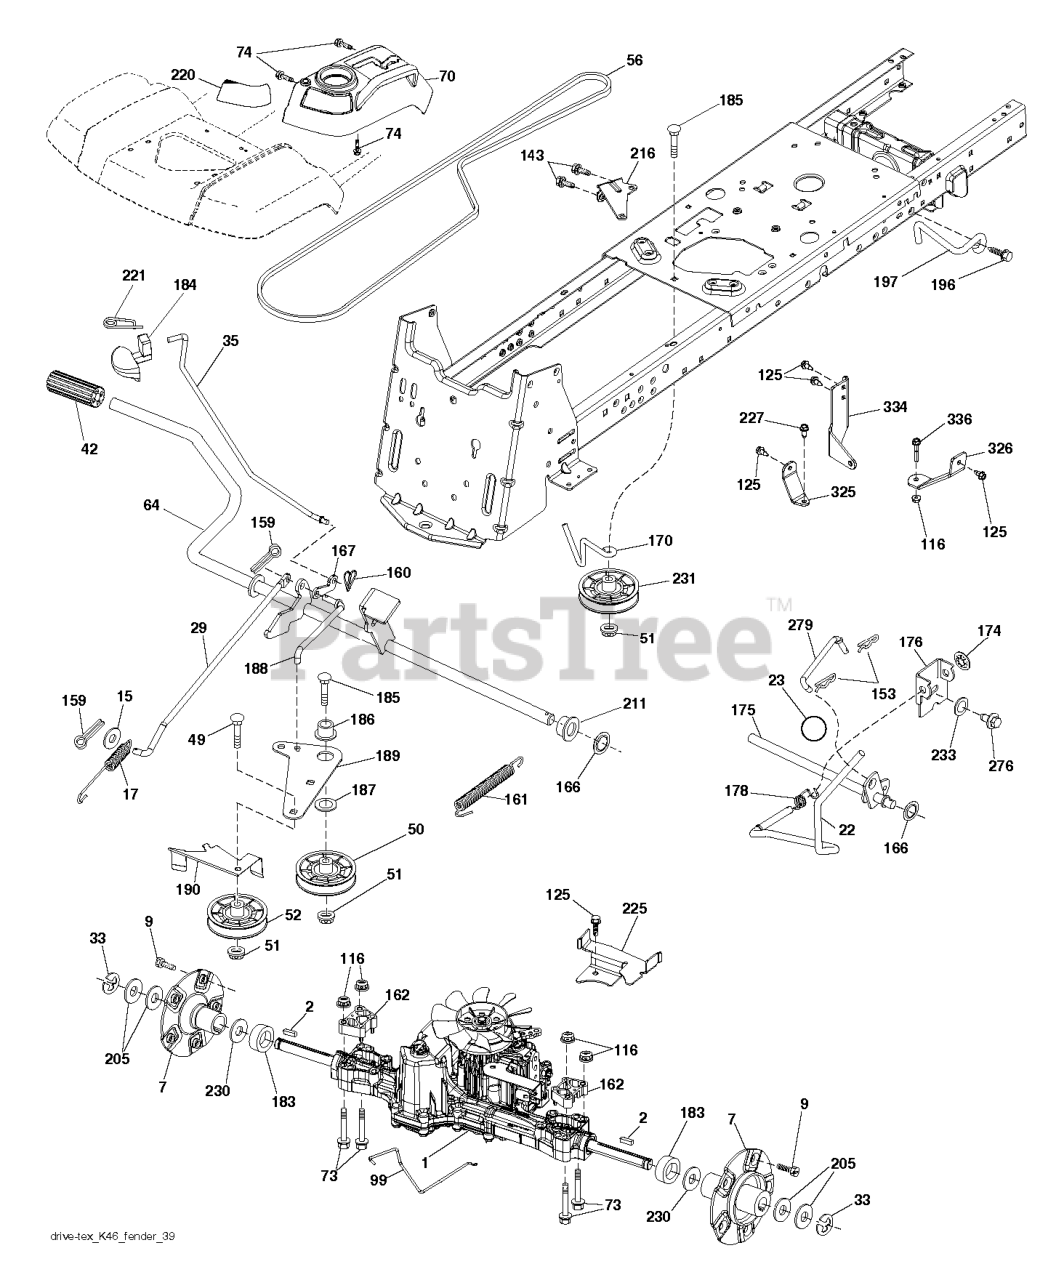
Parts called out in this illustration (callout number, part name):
2	KEY.SQUARE.187X2.500
7	HUB.ASM.WHEEL.REAR.22"
9	HUB BOLT
15	WASHER
17	SPRING.BRAKE.K46.GREEN
22	ROD.SHIFT.FENDER.STGT.
23	KNOB.DELUXE.(PISTOL.GRIP).BLAC
29	ROD.BRAKE.K46
35	ROD .BRAKE. PARKING. GT. HUSQ.
42	PEDAL COVER T
50	IDLER.FLAT.910.OFFSET
51	NUT LOCK FLG 3/8-16 UNC
52	IDLER.V-GROOVE.910.OFFSET
56	V-BELT.MOWER.92.40.42/K46
64	SHAFT.ASM.PEDAL.BRAKE.
70	SUBASM.CONSOLE.HUSQ.GT.HYDRO
73	BOLT.HEX.FLNG.5/16-18X3.75
74	SCREW.HI-LO.CONSOLE
99	ROD.SPRING.BYPASS.K46.TEX.GT
116	NUT LOCK HEX FLANGE 5/16-18
125	SCREW
143	SCREW LT
153	RETAINER M
159	COTTER PIN
160	RETAINER CLIP
161	SPRING, RETURN LT
162	SPACER.TRANSAXLE.1"
166	NUT.PUSH.625
167	LATCH.BRAKE.SPRING
170	KEEPER.CENTER SPAN.1.688
174	NUT.PUSH.500.2006
175	SHAFT ASM SHIFT
176	ARM.CLEVIS.ROD.SHIFT
178	SPRING.SHIFT.GT2006
183	SPACER.SPLIT.800X.350
184	HANDLE.PARKING.BRAKE.H (BLK)
186	SPACER.RETAINER
187	WASHER 12/32X2X10GA
188	RP.LINK.CLUTCH.GROUND.DRIVE
189	BELLCRANK.GROUND.DRIVE.TEX.
190	KEEPER.BELLCRANK.DRIVE
196	SCREW 3/8-16X1
197	CLUTCH.ANTIROTATION.WIREFORM.
211	BUSHING.SHAFT.BRAKE.HAND
216	BRACKET.PULLEY.IDLER.W/TEX
220	REFLECTOR.RH.TEX GT
221	RETAINER.SPRING.CLIP.H
225	KEEPER.BELT.TRANSAXLE.K46
227	SCREW.THDROL.5/16-18X3/4.TTY
230	WASHER.HARDENED
231	IDLER.V-GROOVE.1.688.OFFSET
233	WASHER SERRATED
276	BOLT FIN HEX 7/16-14 X 1
279	LINK.SHIFT.T/A.K46.FEND.TX
325	BRACKET.TRQ.STP.46.22".TIRE.LH
326	BRACKET.TRQ.STP.46.22".TIRE.RH
334	SWAY.ROD.BRACKET.K46.X431
336	BOLT.5/16-18X1-3/4.FLANGED.HEX
